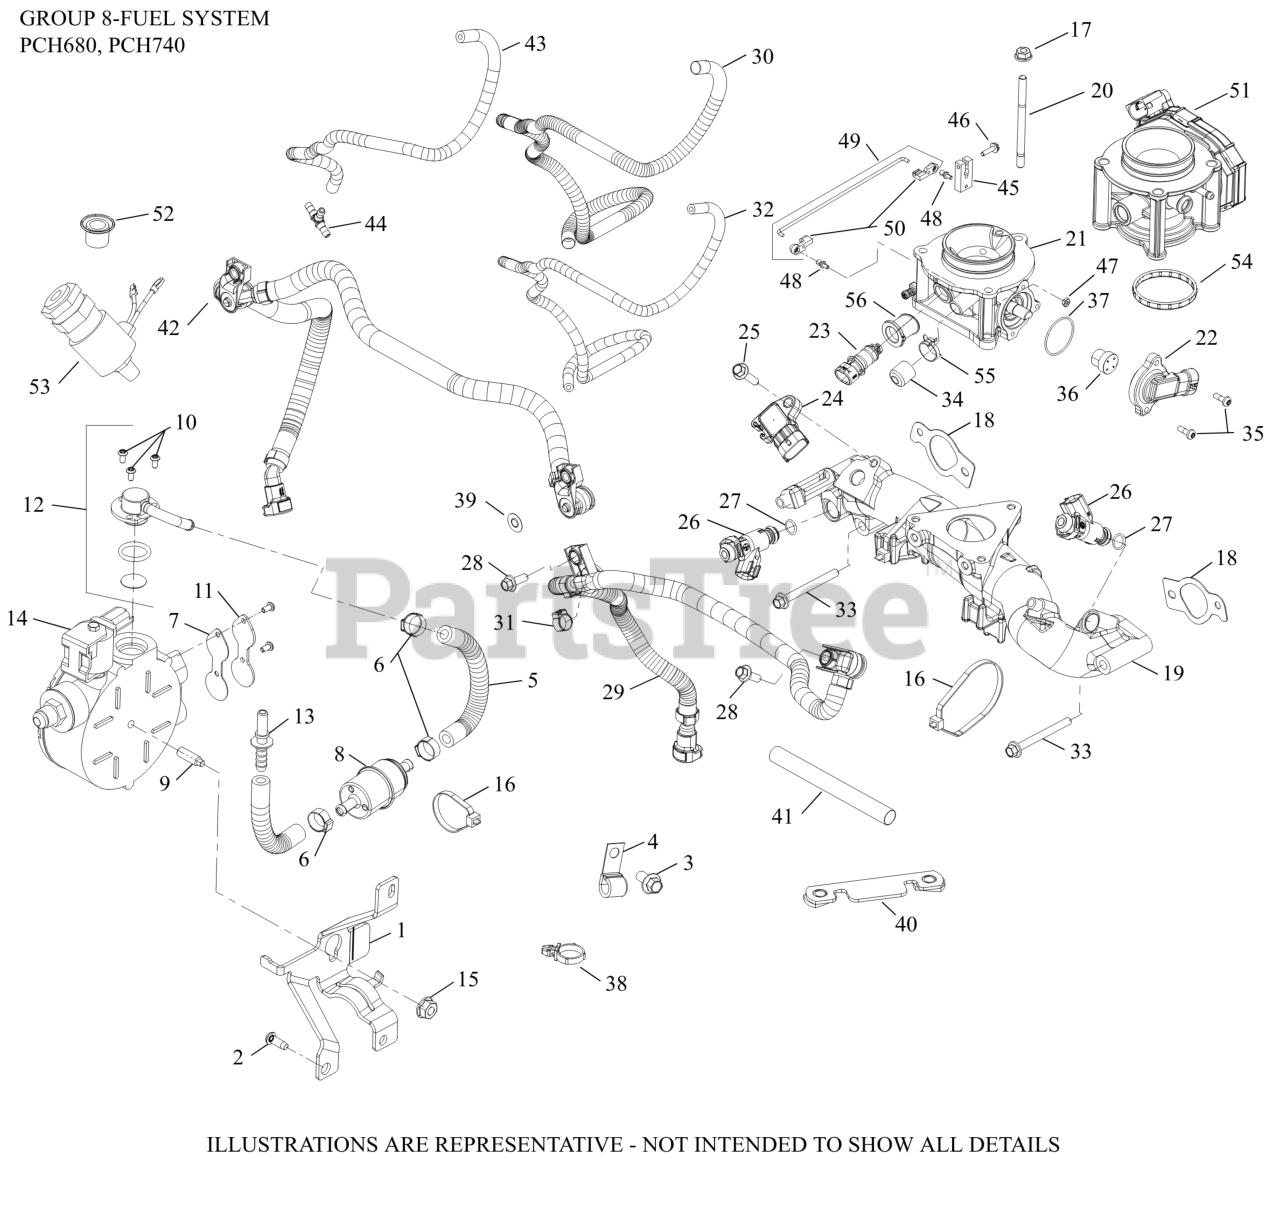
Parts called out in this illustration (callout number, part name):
1	BRACKET, LP REGULATOR
2	SCREW, THREAD FORMING
3	SCREW, FLG 8X1.25X16
5	HOSE, FUEL LOW PROPANE
6	CLAMP, HOSE
8	PROPANE FUEL FILTER-(#2505050S)
9	STUD, LP REGULATOR
10	SCREW, STARTER SWITCH
11	COVER, OIL PORT
12	KIT, OUTLET FITTING W/O-RING LPG
12	KIT, PLUG W/O-RING LPG (A7-173)
13	FITTING, FUEL - STRAIGHT
14	REGULATOR, W/RTV
15	NUT, FLG M8X1.25
17	NUT, FLG M6X1.0
18	GASKET, INTAKE MANIFOLD-USE 24 041 79-S
19	KIT, MANIFOLD
20	STUD,M6X1.0X84
21	BODY, THROTTLE ASM W/ PIN (30)
22	SENSOR, THROTTLE POSITION
24	SENSOR, T-MAP
26	INJECTOR, GASEOUS FUEL
27	KIT, FUEL INJECTOR O-RING
28	SCREW, FLG M6x1.0x20
29	FUEL HOSE ASSY(ECV,FCV,EZT,EKT,PCH,PCV)
30	SLEEVE, ANTI-ABRASION
30	SLEEVE, ANTI ABRASION
32	HOSE, EVAPORATIVE
33	SCREW, FLG M6X1.0X60
34	CAP, MASKING
36	MAGNET ASSEMBLY, TPS
37	O-RING, TPS SENSOR
38	CLIP, SNAP-IN-USE 25 018 05-S
39	CLIP, RETAINER
40	BRACKET, MOUNTING
41	SLEEVE, ANTI ABRASION -USE 25 431 12-S
42	RAIL, FUEL - ASSEMBLY (ECV850-880)
NI	RETAINER, WIRE HARNESS
NI	KIT, LOCK-OFF ASSY LPG (A7-175)
NI	KIT, VAPORIZER FILTER REPL'MT LPG(A7-170
